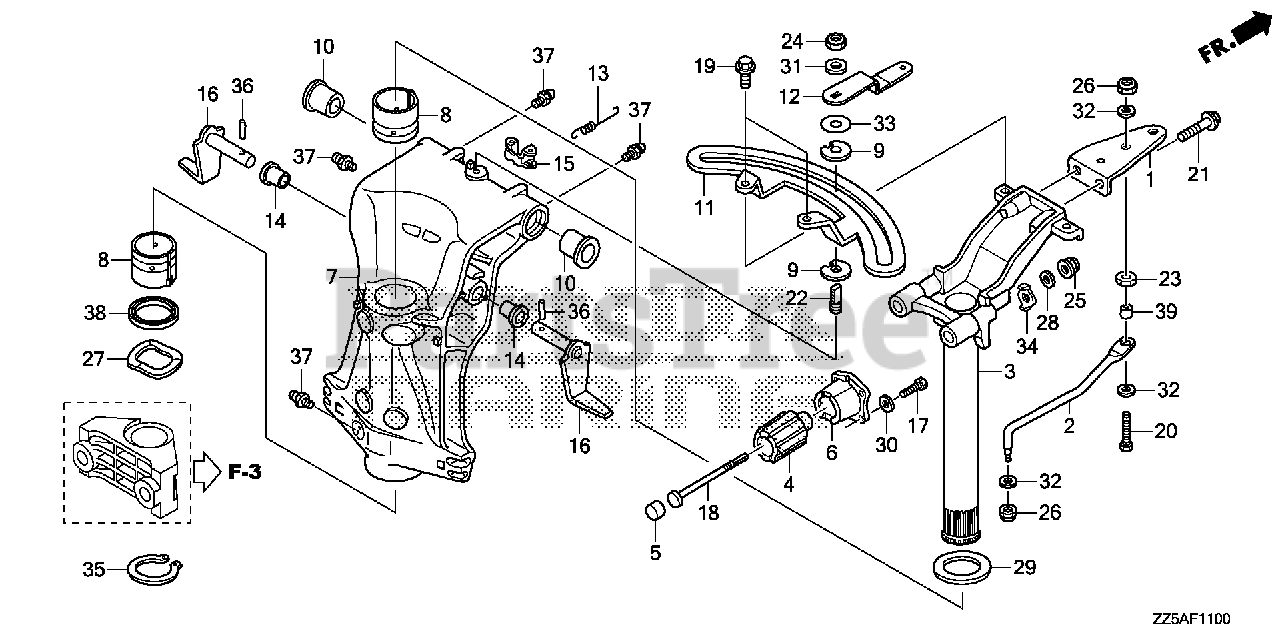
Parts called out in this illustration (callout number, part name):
1	PLATE, STEERING
2	ROD, STEERING
3	FRAME, MOUNTING
4	RUBBER, MOUNTING (UPPER)
5	RUBBER, MOUNTING (UPPER) (B)
6	HOLDER, MOUNTING (UPPER)
7	CASE, SWIVEL *NHB14M* (AQUA MARINE SILVER METALLIC)
8	LINER, SWIVEL CASE
10	BUSH, SWIVEL CASE
13	SPRING, TILT LEVER
14	BUSH, TILT ARM
15	BRACKET, TILTING
16	STOPPER, TILT
17	BOLT, HEX. (6X18)
18	BOLT, SPECIAL (10X130)
20	BOLT (3/8-24UNF)
21	BOLT, FLANGE (10X25)
23	NUT (3/8-24UNF)
25	NUT, FLANGE (10MM)
26	NUT, SELF-LOCK (3/8-24UNF)
27	WASHER, WAVE (40MM)
28	WASHER, PLAIN (10MM)
29	WASHER, THRUST (34MM)
30	WASHER, PLAIN (6MM)
32	WASHER (10MM)
34	WASHER, SPECIAL
35	CIRCLIP (OUTER) (39MM)
36	PIN, SPRING (2.5X20)
37	NIPPLE, GREASE
38	OIL SEAL (39.5X52X6) (ARAI)
39	COLLAR, STEERING ROD
